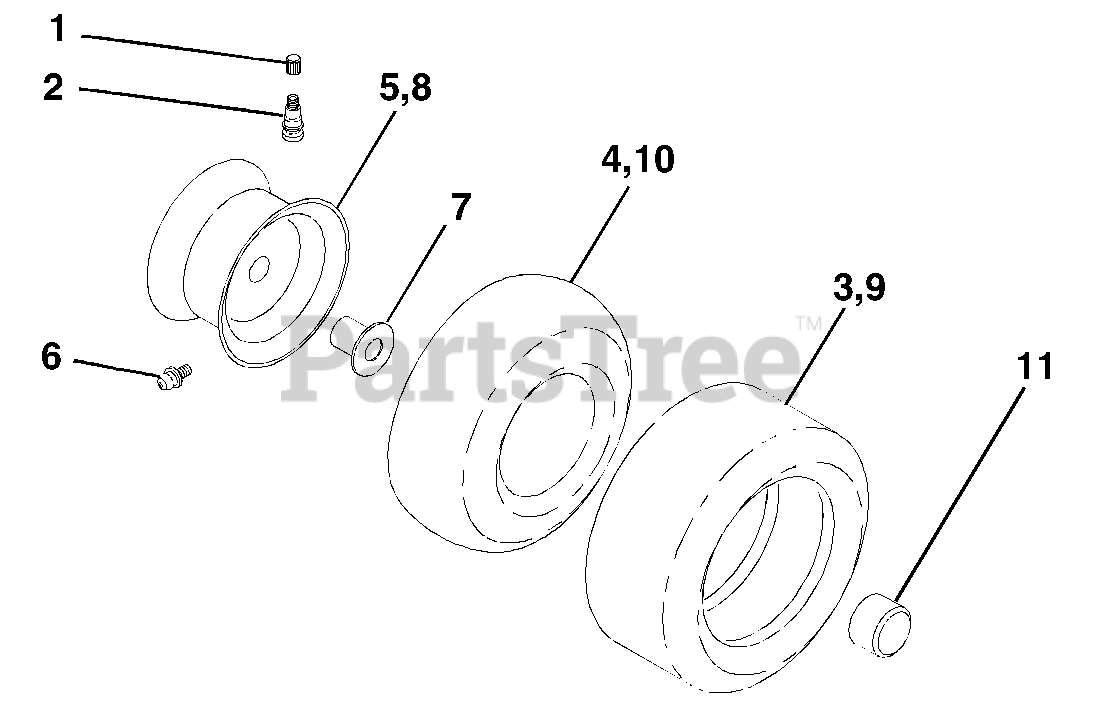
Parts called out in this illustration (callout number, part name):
1	Cap Valve Tire
2	Stem Valve
3	Tire F Ts 15 X 6 0 - 6 Service
4	Tube Front (Service Item Only)
5	Rim Asm 6"front Silver Service
6	Fitting Grease (Front Wheel Only)
7	Bearing Flange (Front Wheel Only)
8	Rim Asm 8"rear Silver Service
9	Tire R Ts 18x9 5-8 C Service
10	Tube Rear (Service Item Only)
11	Cap Axle Blk 1 50 X 1 00
